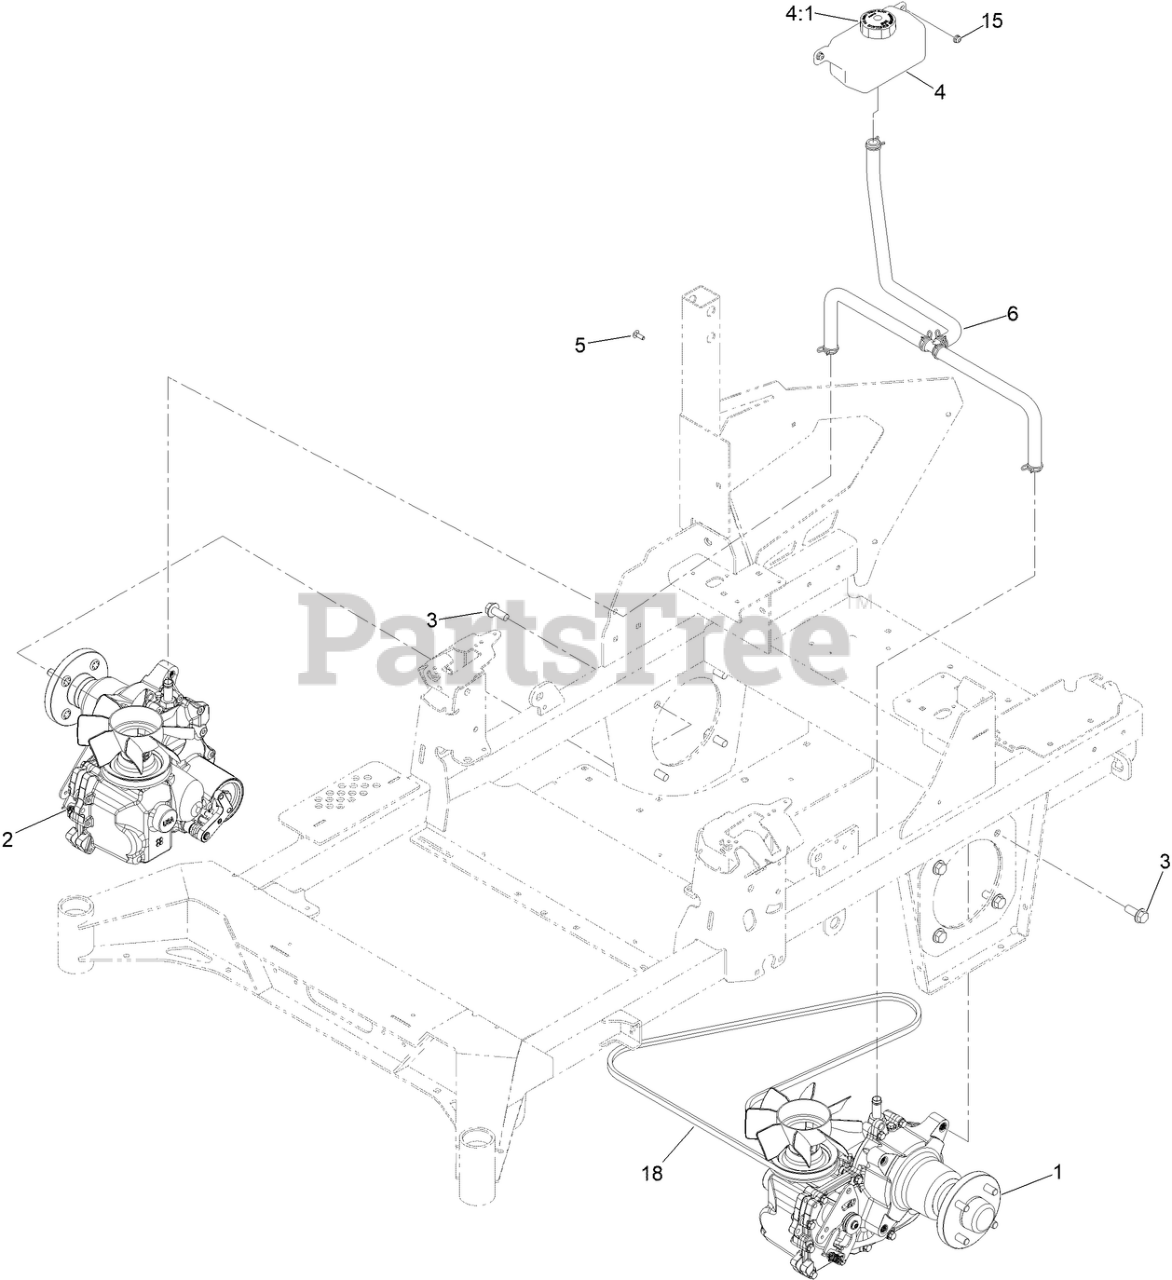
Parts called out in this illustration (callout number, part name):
1	LH TRANSAXLE ASM W/ARM
2	RH TRANSAXLE ASM W/ARM
3	SCREW-HHF
4	HYDRAULIC RESERVOIR ASM
4:1	CAP-RESERVOIR, HYD
5	SCREW-CARR
6	ASM-HOSE, HYDRAULIC
15	NUT-HF
18	BELT-V
